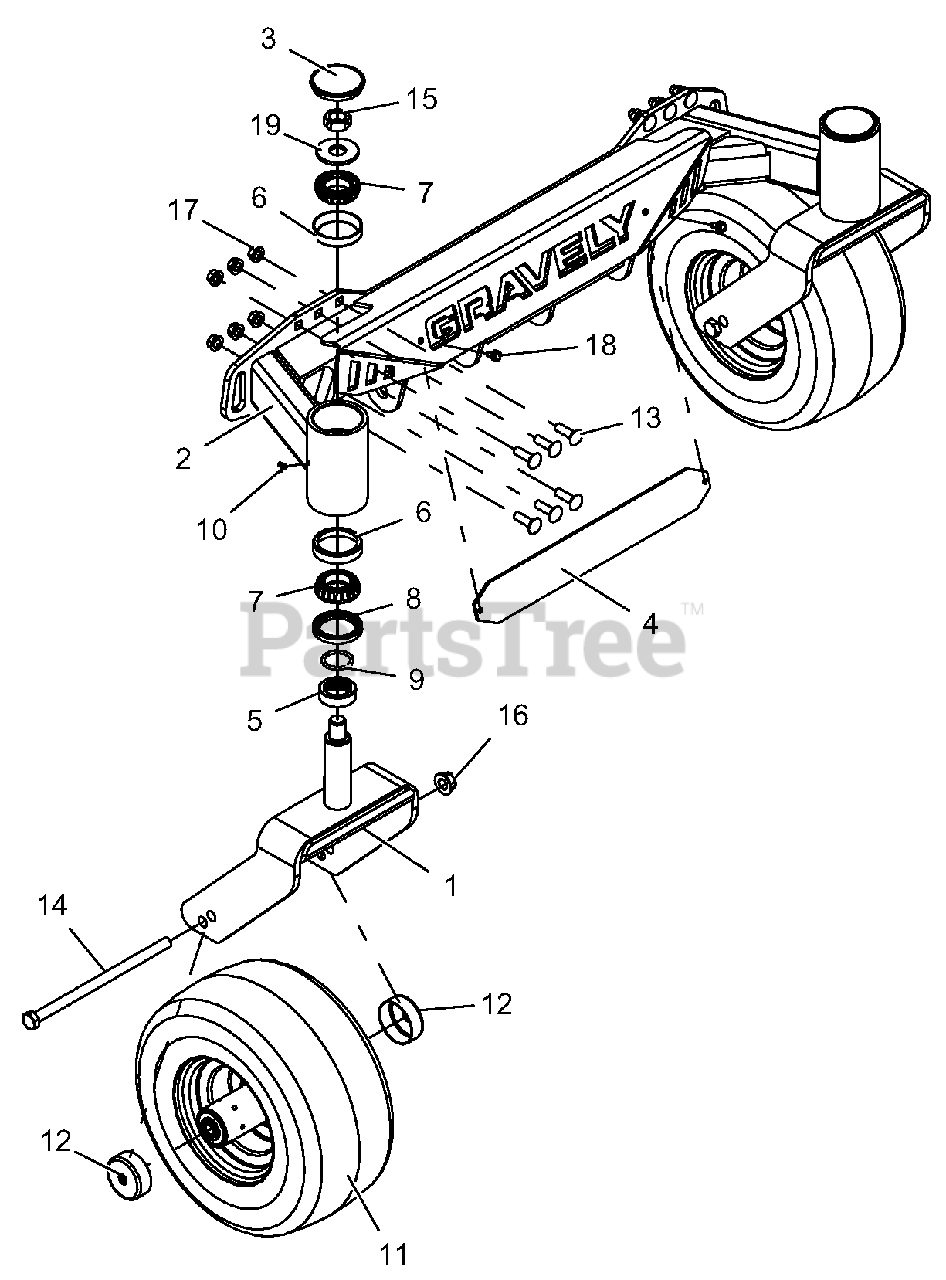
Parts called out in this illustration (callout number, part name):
1	WMT, CASTER FORK - RED
2	WLDMT, FRONT AXLE 48" - RED
3	CAP, DUST
4	PLATE, BACK NAME - BLACK
5	SPCR, FRONT CASTER FORK
6	BRG, CUP 2.328 x .465
7	BRG, CONE 1.25 x .66
8	SEAL, OIL 1.75 x 2.332 x .312
9	O-RING, .139 W x 1.234 ID
10	PLUG, .250-28 x .185 HEX HEAD
11	TIRE/WHEEL, 13 x 6.50-6 SEMI PNEU
12	SHIELD, WHEEL BEARING
13	BLT-RDHDSQNK .38-16 x 1.25 G5 YWZC
14	BLT-HEX .50-13 x 9.00 GR5 YWZC
15	@NUT-LK-CTR-JAM .75-16 YWZC
16	NUT-LK-NYL-FLG .50-13 YWZC
17	NUT, LK-TOP-FLG .38-16 YWZC
18	SCR-TAP .25-20 x .50 HWH TR YWZ
19	WSHR-FL-STL .812 x 2.00 x .148 YWZC
